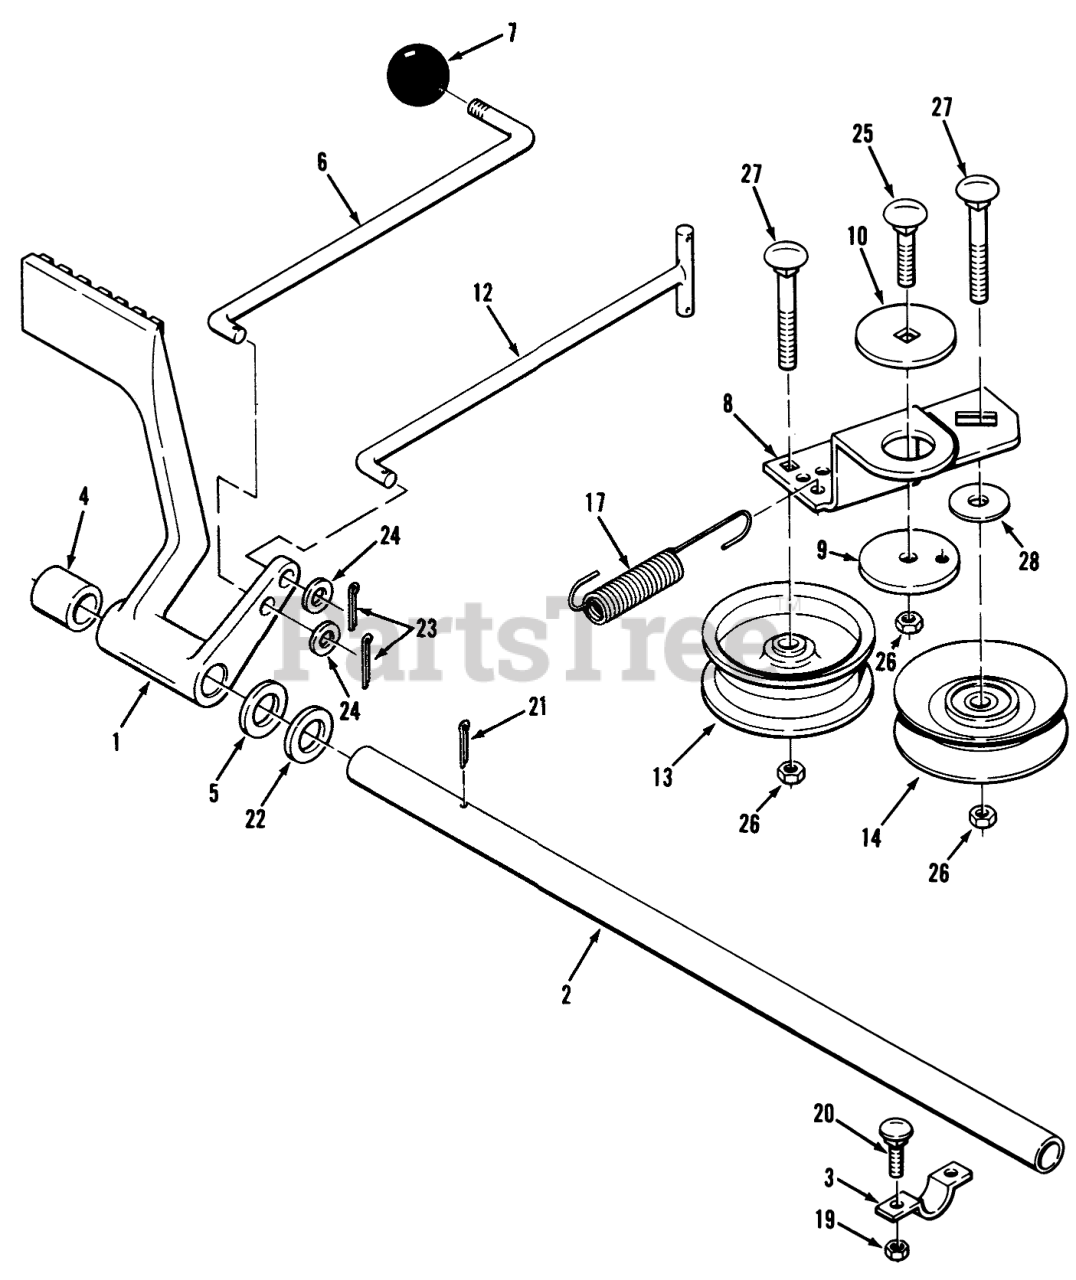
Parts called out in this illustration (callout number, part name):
1	PEDAL-BRAKE R
2	SHAFT PEDAL
3	CLAMP
4	Spacer
5	WASHER-WAVE
6	ROD-BRAKE LOCK B
7	KNOB
8	ARM-IDLER R
9	BUSHING
10	WASHER-BEARING
12	ASSY-ROD FRONT BR
13	PULLEY IDLER
14	PULLEY-IDLER
17	SPRING
19	Nut
20	Bolt
22	Washer
23	Cotter Pin
24	WASHER 5/16 SAE
25	Bolt
26	NUT
27	Carriage Bolt 3/8-16 x 1-3/4
28	Washer
